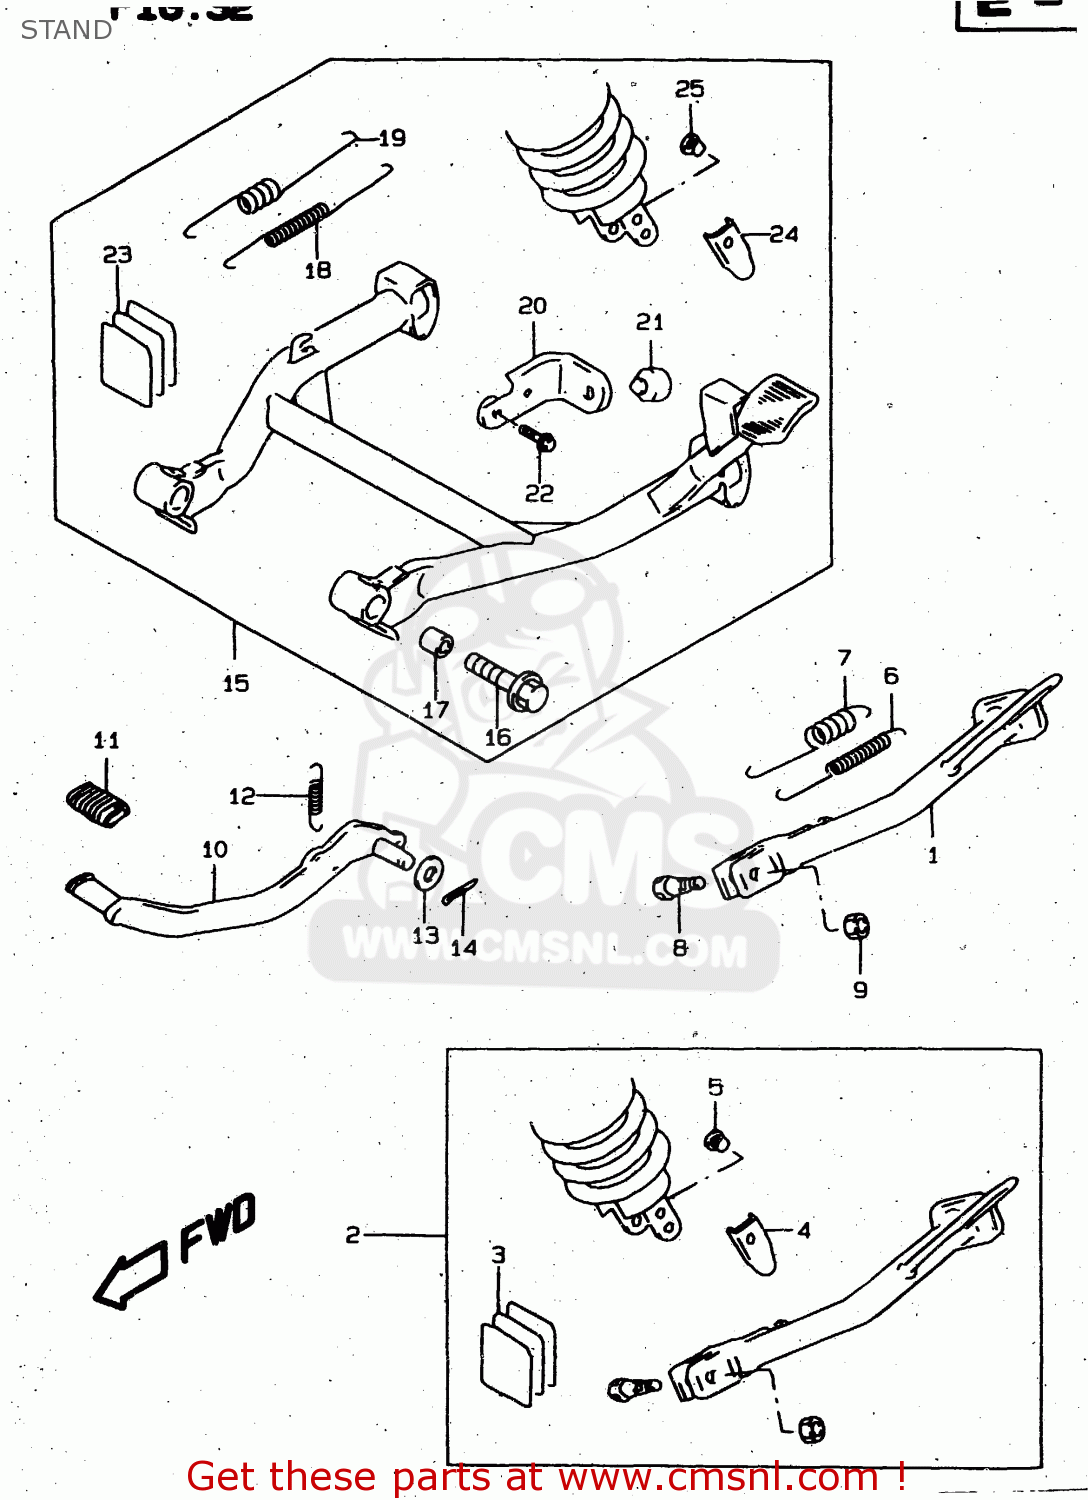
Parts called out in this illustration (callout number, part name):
1	STAND COMP,PRO
2	STAND SET,PROP
3	LABEL SET,SEAT HEIGHT WARNING
4	PLATE,RR SHOCK ABSORBER LWR
5	PLUG
6	SPRING
7	SPRING
8	BOLT(10X30)
9	NUT
10	PEDAL,BRAKE
11	RUBBER,PEDAL
12	SPRING
13	WASHER(15.5X26X2.3)
14	COTTER PIN
15	STAND,CNTR HIGH
16	BOLT(10X48)
17	SPACER(10X16X25.5)
18	SPRING
19	SPRING OUTER
20	PLATE,CTR STAND CUSHION
21	CUSHION
22	BOLT
23	LABEL SET
24	PLATE,RR SHOCK ABSORBER LWR
25	PLUG
